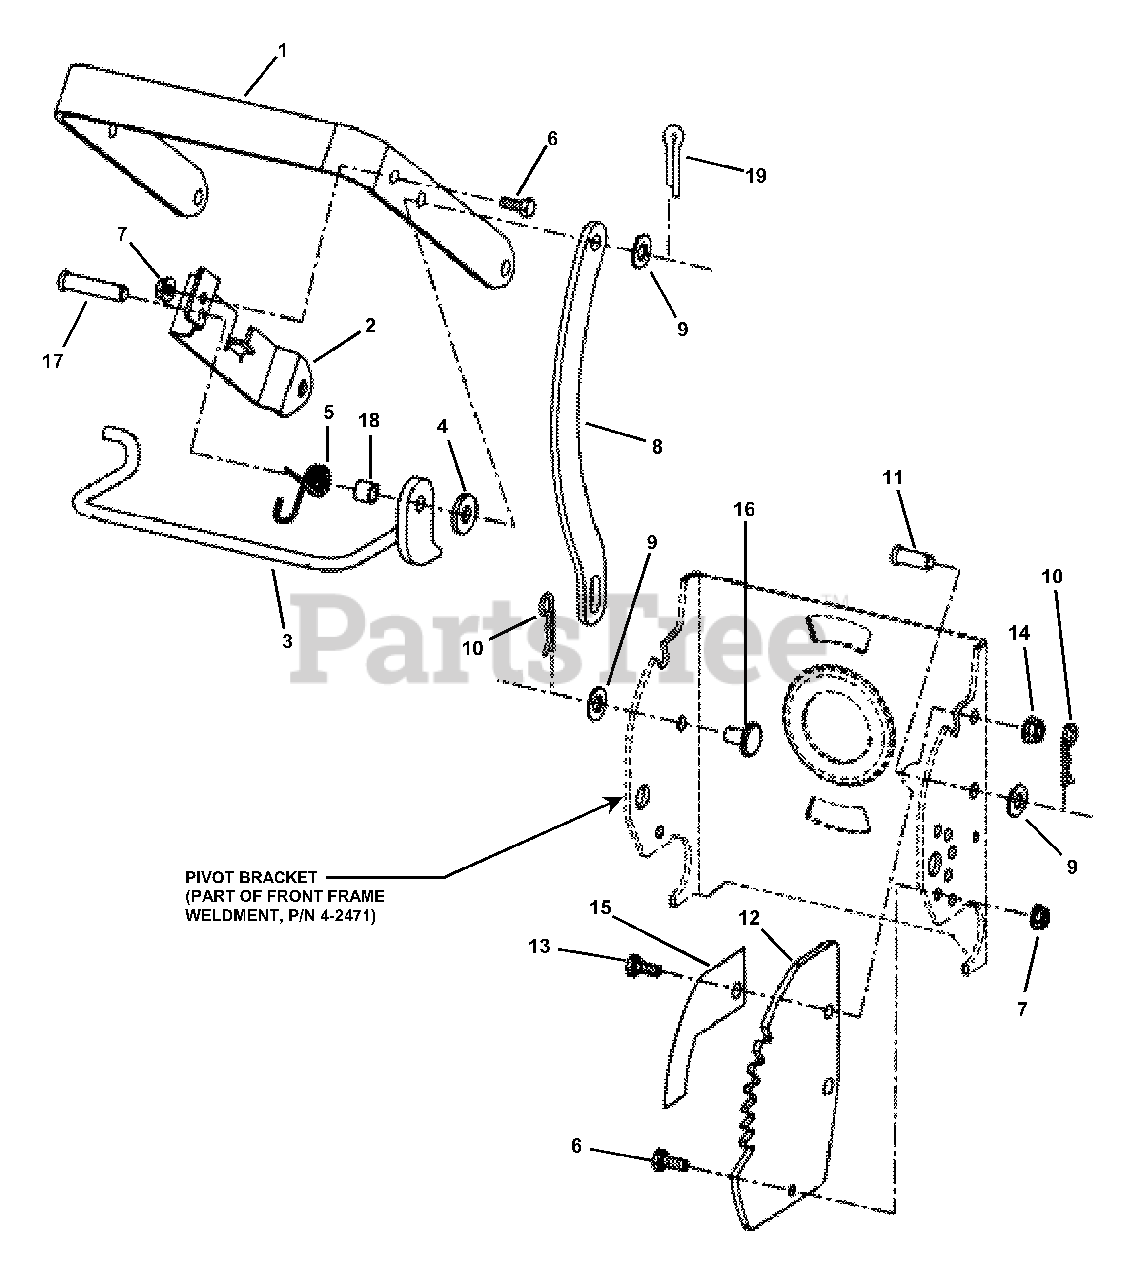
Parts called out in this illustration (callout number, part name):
1	HANDLE, Deck Lift
2	BRACKET, Pivot Support
3	LEVER, Deck Lift/Handle Release (Series 2)
4	WASHER, Slipper
5	SPRING, Torsion (Deck Position)
6	SCREW, 1/4-20 x 5/8" Hex head Cap, Gr. 5
7	NUT, 1/4-20 Hex Flange Lock
8	BAR, Deck Lift
9	WASHER, 3/8" Flat
10	HAIRPIN, 3/32 x 1-1/2"
11	PIN, 3/8 x 7/8" Large Head Clevis
12	PLATE, Detent (Series 2)
13	SCREW, 5/16-18 x 3/4" Hex Cap, Gr.5
14	NUT, 5/16-18 Hex Flange Lock, Gr.5
15	DECAL, Deck Position
16	PIN, 3/8 x 1/2" Expanded Head Clevis
17	PIN, 3/8 x 1-5/8" Clevis
19	PIN, 3/32" x 3/4" Cotter
